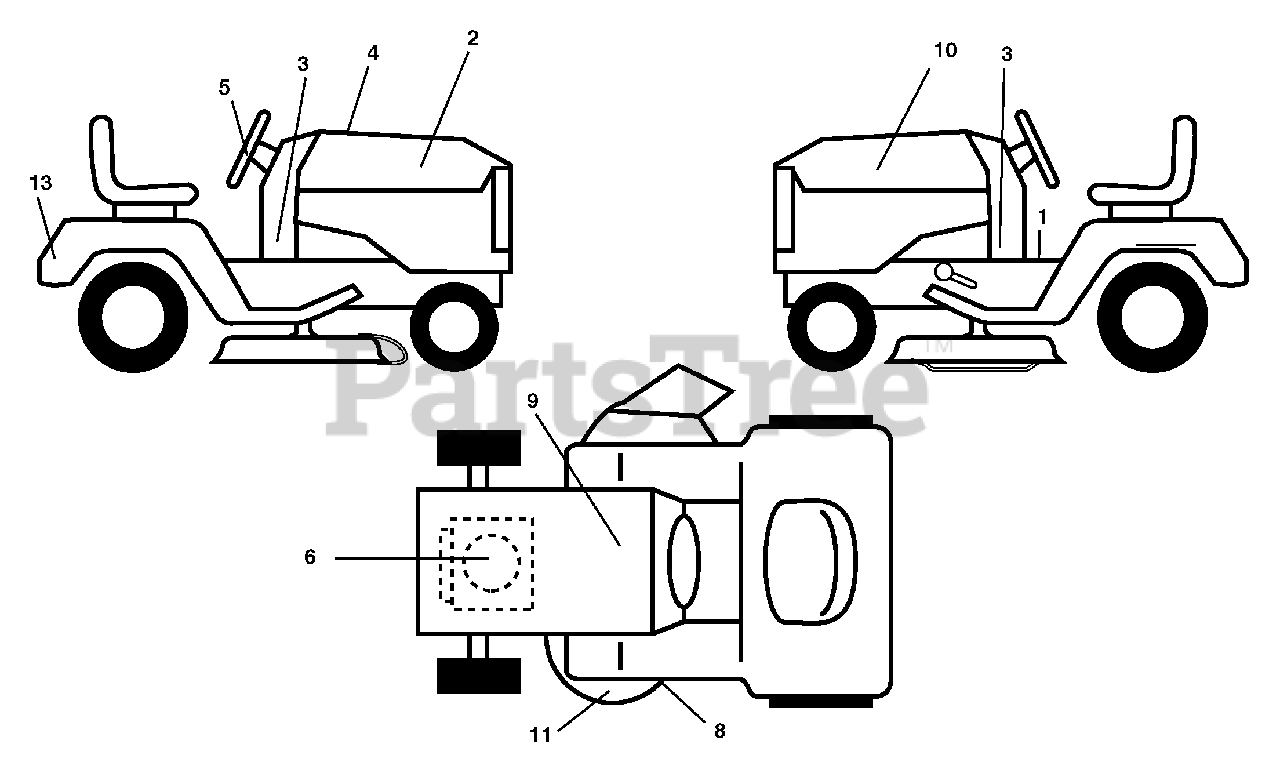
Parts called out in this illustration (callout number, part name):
1	Decal, Operator's
2	Decal, Hood RH
3	Decal, Dash Lower
4	Decal, Replacement
5	Decal, Strg Whl
6	Decal, Engine HP
8	Decal, Mower Sch.
9	Decal, Battery Dnge/Poi
10	Decal, Hood LH
11	Decal, Mower Caution
13	Decal, Fender
